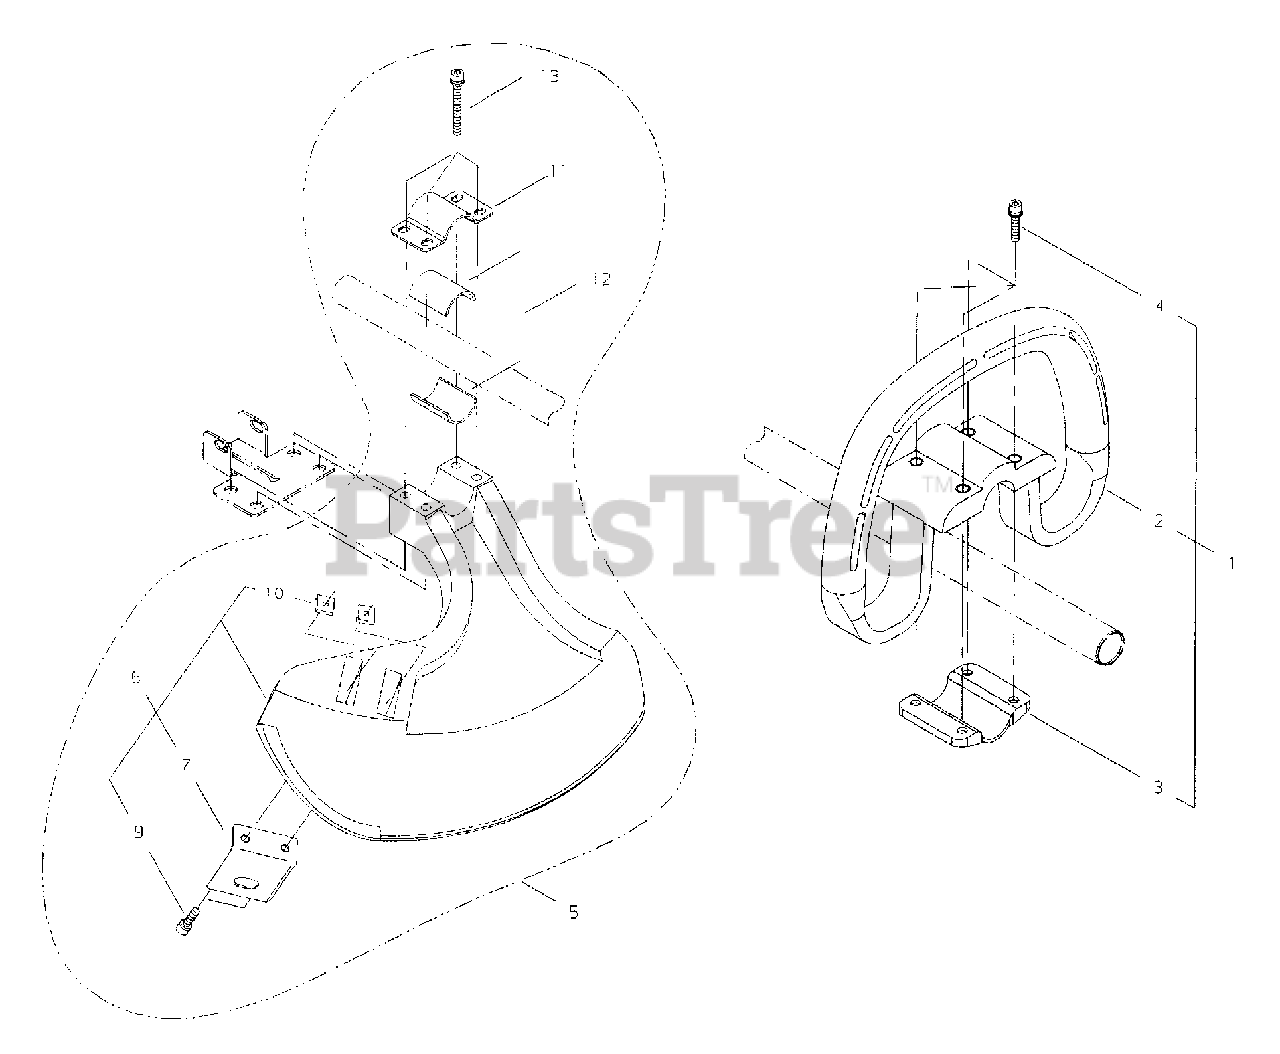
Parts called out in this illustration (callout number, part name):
1	HANDLE ASSY
2	HANDLE
3	SCREW - 5X35
4	NUT - 5
5	DEBRIS SHIELD KIT
6	DEBRIS SHIELD ASSY
7	KNIFE, TRIMMER LINE
9	SCREW - 5X16
10	KNIFE, TRIMMER LINE
11	CLAMP - UPPER
12	SPACER
13	SCREW - 5X45
